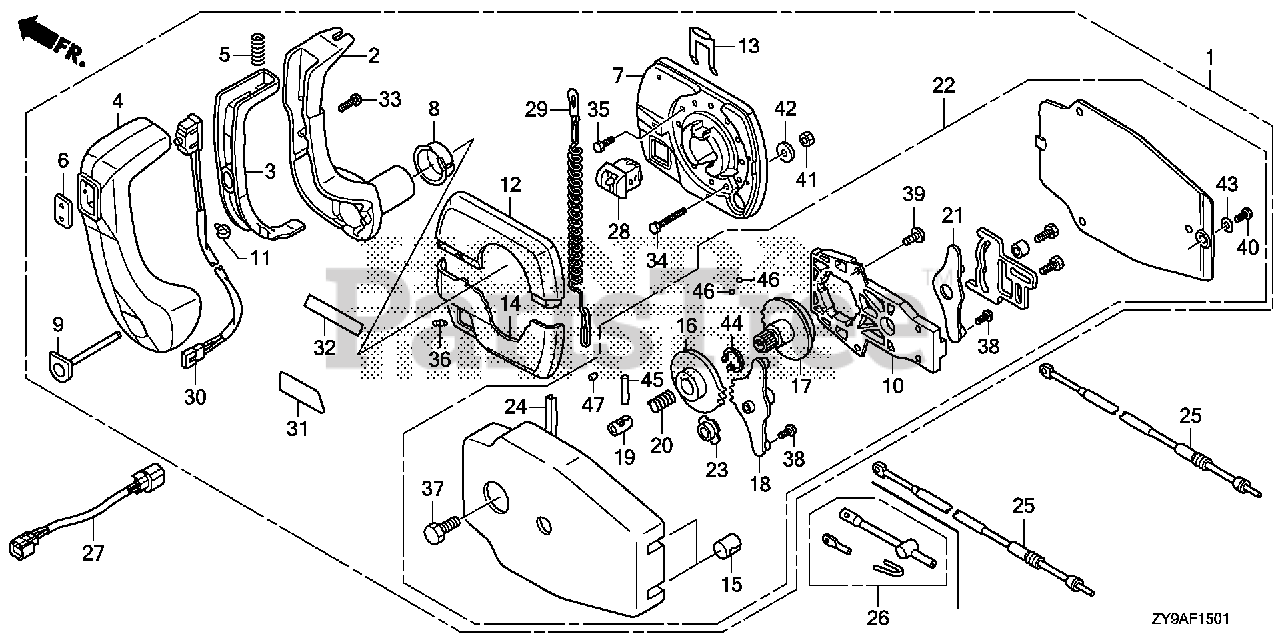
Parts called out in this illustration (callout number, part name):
1	BOX ASSY., REMOTE CONTROL (PANEL MOUNT) (NA USE ALT:06240-ZW7-U00)
2	HANDLE, REMOTE CONTROL
3	LEVER, HANDLE LOCK
4	GRIP, REMOTE CONTROL HANDLE
5	SPRING, REMOTE CONTROL HANDLE
6	COVER, GRIP
7	HOUSING ASSY., REMOTE CONTROL BOX (A)
8	BUSHING Use up to Frame SN 4000953.
9	BUTTON, THROTTLE
10	FRAME ASSY., REMOTE CONTROL BOX
11	BAND B, CABLE Use up to Frame SN 4000953.
12	HOUSING ASSY., REMOTE CONTROL BOX (B)
13	RETAINER
14	HOUSING, REMOTE CONTROL BOX (C)
15	GROMMET
16	WHEEL, CONTROL
17	SHAFT, HANDLE (N/A: SEE ASSEMBLY) (NOT AVAILABLE)
18	ARM ASSY., SHIFT LINK
19	SHAFT, GEARSHIFT
20	SPRING, GEARSHIFT
21	ARM ASSY., THROTTLE LINK
22	HOUSING ASSY. (INNER) (PANEL MOUNT)
23	BUSH
24	SPRING
25	CABLE, REMOTE CONTROL (10'') (TELEFLEX)
25	CABLE, REMOTE CONTROL (10') (NOT AVAILABLE)
25	CABLE, REMOTE CONTROL (11') (TELEFLEX)
25	CABLE, REMOTE CONTROL (1 1'') (BRUNSWICK) (NOT AVAILABLE)
25	CABLE, REMOTE CONTROL (12') (TELEFLEX)
25	CABLE, REMOTE CONTROL (1 2'') (BRUNSWICK) (NOT AVAILABLE)
25	CABLE, REMOTE CONTROL (13') (TELEFLEX)
25	CABLE, REMOTE CONTROL (1 3'') (BRUNSWICK) (NOT AVAILABLE)
25	CABLE, REMOTE CONTROL (14') (TELEFLEX)
25	CABLE, REMOTE CONTROL (1 4'') (BRUNSWICK) (NOT AVAILABLE)
25	CABLE, REMOTE CONTROL (15') (TELEFLEX)
25	CABLE, REMOTE CONTROL (1 5'') (BRUNSWICK) (NOT AVAILABLE)
25	CABLE, REMOTE CONTROL (16') (TELEFLEX)
25	CABLE, REMOTE CONTROL (1 6'') (BRUNSWICK) (NOT AVAILABLE)
25	CABLE, REMOTE CONTROL (17'') (TELEFLEX)
25	CABLE, REMOTE CONTROL (1 7'') (BRUNSWICK) (NOT AVAILABLE)
25	CABLE, REMOTE CONTROL (18') (TELEFLEX)
25	CABLE, REMOTE CONTROL (1 8'') (BRUNSWICK) (NOT AVAILABLE)
25	CABLE, REMOTE CONTROL (19') (TELEFLEX)
25	CABLE, REMOTE CONTROL (1 9'') (BRUNSWICK) (NOT AVAILABLE)
25	CABLE, REMOTE CONTROL (20') (TELEFLEX)
25	CABLE, REMOTE CONTROL (2 0') (BRUNSWICK) (NOT AVAILABLE) (ALT. PNO: 24920-ZW1-003AH)
26	ADAPTER, REMOCON CABLE (N/A: USE 24931-ZW1-000)
27	HARNESS ASSY., POWER TRIM-TILT Use from Frame SN 4000954.
28	SWITCH ASSY., EMERGENCY STOP
29	WIRE, EMERGENCY
30	SWITCH ASSY., POWER TRIM-TILT (A) Use up to Frame SN 4000953.
31	MARK, REMOTE CONTROL (A)(PANEL)
32	MARK, REMOTE CONTROL (B)(FOR STARBOARD)
32	MARK, REMOTE CONTROL (C)(FOR PORT)
33	SCREW A (NOT AVAILABLE)
34	SCREW B
35	SCREW C
36	SCREW SET (1/4-20X16") Use up to Frame SN 4000953.
37	BOLT
38	SCREW (8-32X3/8)
39	SCREW (10-32X5/8)
40	SCREW (10-32X5/8)
41	NUT (1/4X20)
42	WASHER
43	WASHER Use up to Frame SN 4000953.
44	CIRCLIP (OUTER)
45	PIN, GEARSHIFT
46	BALL, STEEL
47	ROLLER, SHIFT CLICK
